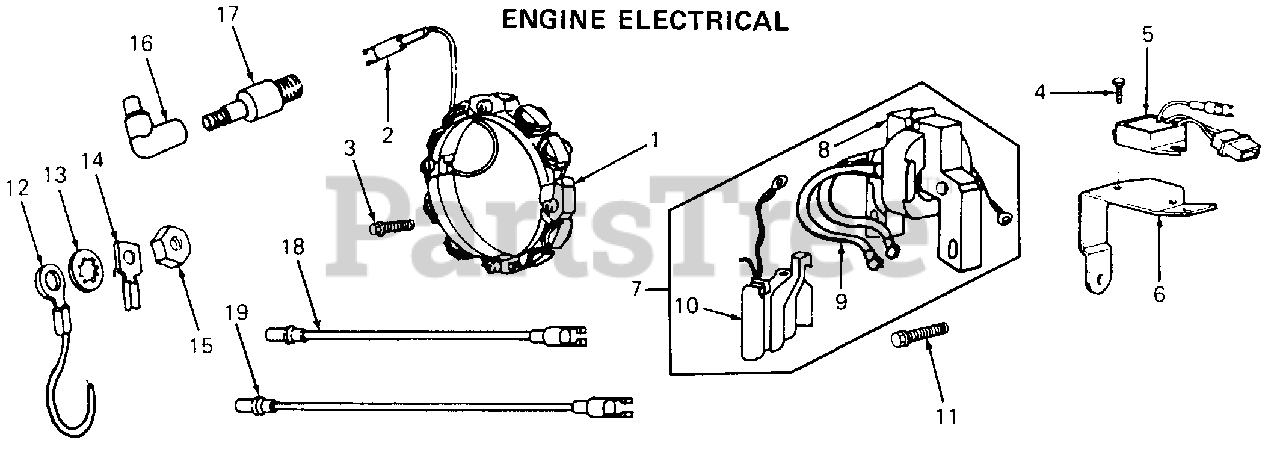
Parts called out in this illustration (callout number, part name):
1	Stator, Alternator (Tri-Circuit System)
2	Connector Assembly (Tri-Circuit System)
3	Screw, Sem
4	Screw, Regulator Mtg
5	Regulator, Alternator (Regulated System)
6	Bracket, Regulator
7	Armature Magnetron
8	Armature Assy
9	Terminal, Ignition Cable
10	Trigger Coil Assy, Magnetron Ignition
11	Screw, Armature Mtg Sem
12	Wire, Ground
13	Washer, Lock, Shakeproof
14	Terminal, Spade
15	Nut, Hex 8-32
16	Elbow, Spark Plug
17	Spark Plug, Resistor
18	Cable, Alternator Extension (Tri-Circuit System)
19	Cable, Magneto Extension (Tri-Circuit System)
